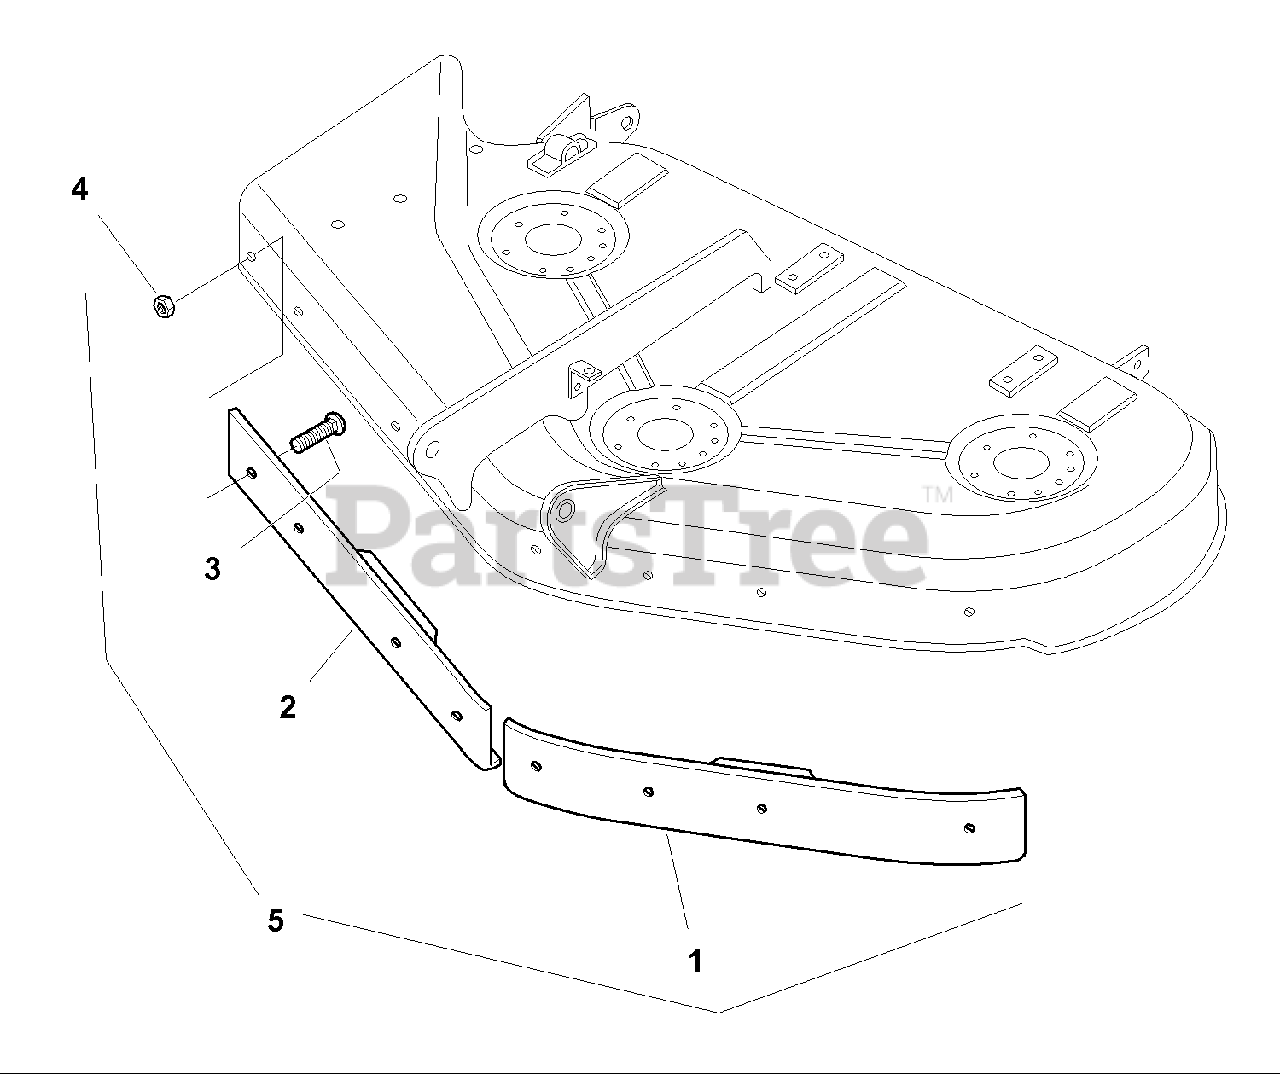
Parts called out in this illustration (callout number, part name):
1	BAFFLE, LH for 44" Mower
2	BAFFLE, RH for 44" Mower
3	CARRIAGE BOLT, 5/16-18 x 5/8
4	NUT, Hex, 5/16-18
5	Anti-Blowout Baffle Kit, (Includes Ref. Nos. 1, 2, 3, 4 & 5)
